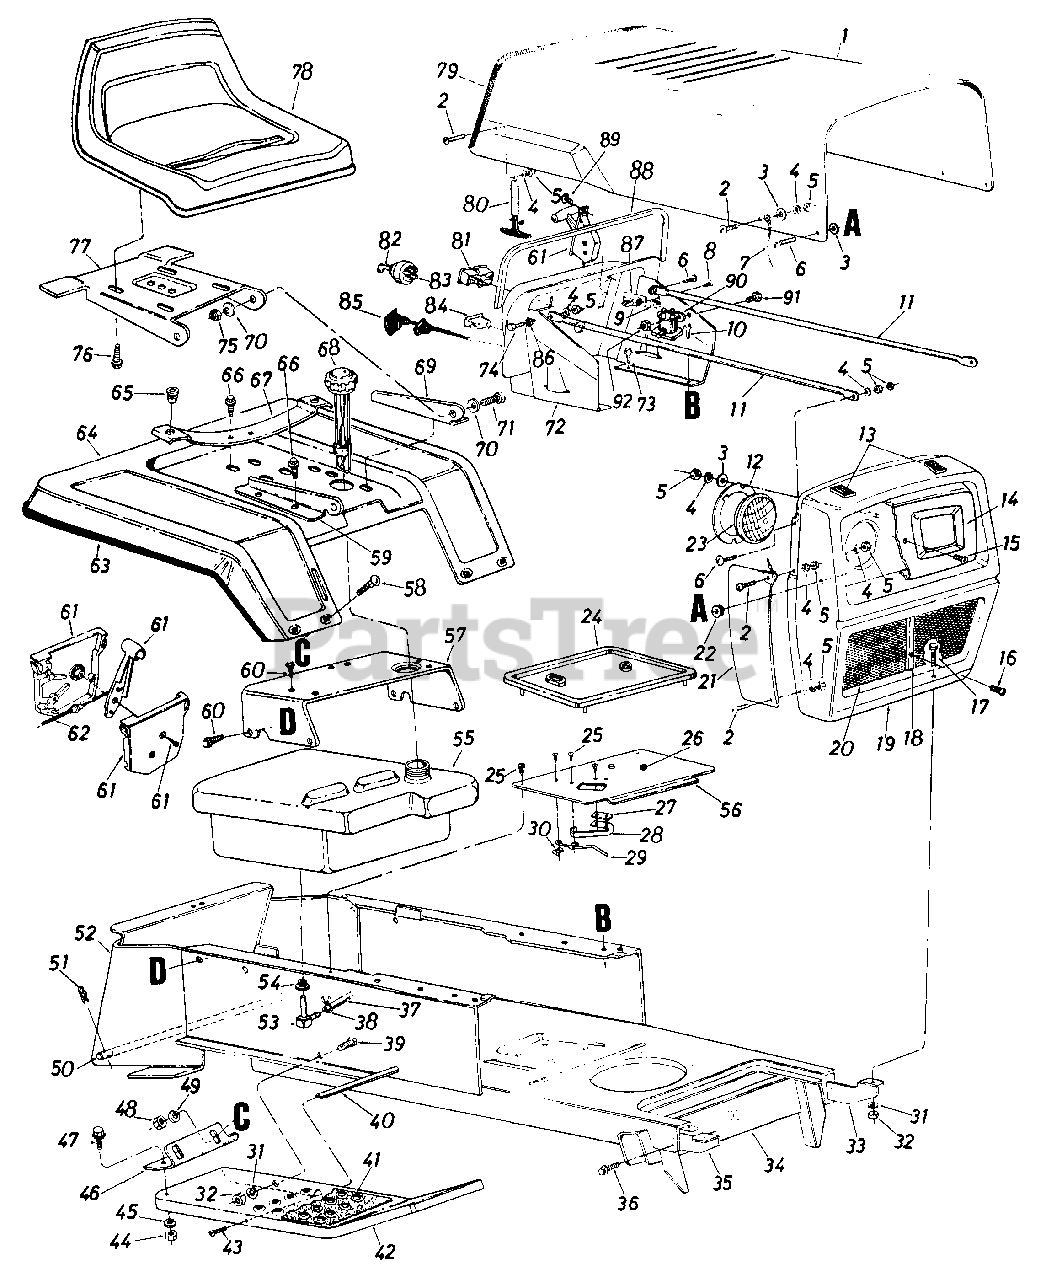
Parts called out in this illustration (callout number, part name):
3	Fl-Wash. 1/4" I.D.
4	L-Wash. 1/4" I.D.*
5	Hex Nut 1/4-20 Thd.
6	Truss Mach. Scr. 1/4-20 x .75" Lg.*
7	Hood Stop
8	Hex Tap Scr. #10 x .50" Lg.
9	Speed Nut #10Z
10	Hex Thd. Rolling Scr. 1/4" x .50" Lg.
11	Grille Positioning Rod
12	Head Lamp Retainer
13	PVC Foam Strip 1/2" X 1.00" x 2.00" Lg.
14	Head Lamp Bezel
15	Truss Mach. Scr. #10-24 x .38" Lg.
16	Truss Mach. Scr. #10-24 x .62" Lg.
17	Hex Bolt 5/16-18 x .75" Lg.
18	Center Moulding
19	Grille Chrome
20	Grille Insert Screen
21	Grille Side Panel R.H.
21	Grille Side Panel L .H.
22	Rubber Wash. .50" I.D. x 1.0" O.D. .25 Thk.
23	Head Lamp
24	Trans. Cover-Bezel
25	Hex AB-Tap Scr. #8 x .50" Lg.
26	Snap Bushing
27	Insulator Nut Plate
28	Switch Spring
29	Shift Lever Spring
30	Speed Nut #10-24 U-Type
31	L-Wash. 5/16" I.D.
32	Hex Nut 5/16-18 Thd.
33	Grille Mount Brkt. L.H.
34	Lower Frame Ass'y.
35	Grille Mount Brkt. R.H.
36	Hex Thd. Rolling Scr. 5/16" x.75" Lg.
37	Gas Line 46" Lg.
38	Hose Clamp 3/8"
39	Hex Bolt 5/16-18 x .75" Lg.
40	Running Board Rod
41	Foot Pad
42	Running Board R.H.
42	Running Board L.H.
43	Truss Mach. Scr. 5/16-18 x .75" Lg.
44	Hex Nut 5/16-18 Thd.
45	Bell-Wash. .34" I.D. x .87 0 O.D.
46	Fender Brkt. R.H.
48	Hex Nut 1/4-20 Thd.
49	L-Wash. 1/4" I.D.
50	Hitch Rod
51	Internal Cotter Pin
52	Hitch Plate
53	90ø Nipple
54	Bushing (Fuel Tank)
55	Fuel Tank
56	Trans. Cover
57	Seat Mounting Channel
58	Carriage Bolt 1/4-20 x .50" Lg.
59	Seat Bracket R.H.
60	Hex Thd. Rolling Scr. 5/16-24 x .75" Lg.
61	Throttle Control Box Ass'y.
62	Throttle Control Wire
63	Trim Strip 81"
66	Hex Wash. Hd. Self-Tap Scr. 5/16-18 x .50" Lg.
67	Seat Spring
68	Gas Cap w/ Gauge
69	Seat Bracket L.H.
70	Bell-Wash. .34" I.D. x .88" O.D.
71	Hex Bolt 5/16-18 x .75" Lg.
72	Dash Panel Ass'y.
73	Hex Thd. Rolling Scr. 5/16-24 x .75" Lg.
74	Truss Mach. Scr. 1/4-20 x 1.0" Lg.
75	Hex Cent. L-Nut 5/16-18 Thd.
76	Hex Wash. Hd. AB-Tap Scr. 3/8 x .75" Lg.
78	Seat Ass'y. (w/o Safety Switch)
78	Seat Ass'y. (w/ Safety Switch)
79	Vinyl Moulding Strip 30"
80	Hood Latch Ass'y.
81	Ammeter
82	Ignition Key
83	Ignition Switch
84	Light Switch
85	Choke Control Comp.
86	External Wash. 1/4" I.D.
87	Circuit Breaker 8 Amp.
88	Vinyl Moulding Strip 29"
89	Truss Mach. AB-Tap Scr. #10 x .50" Lg.
90	Solenoid
91	Hex Bolt 1/4-20 x .50" Lg.
92	Hex Sems Nut 1/4-20 Thd.
